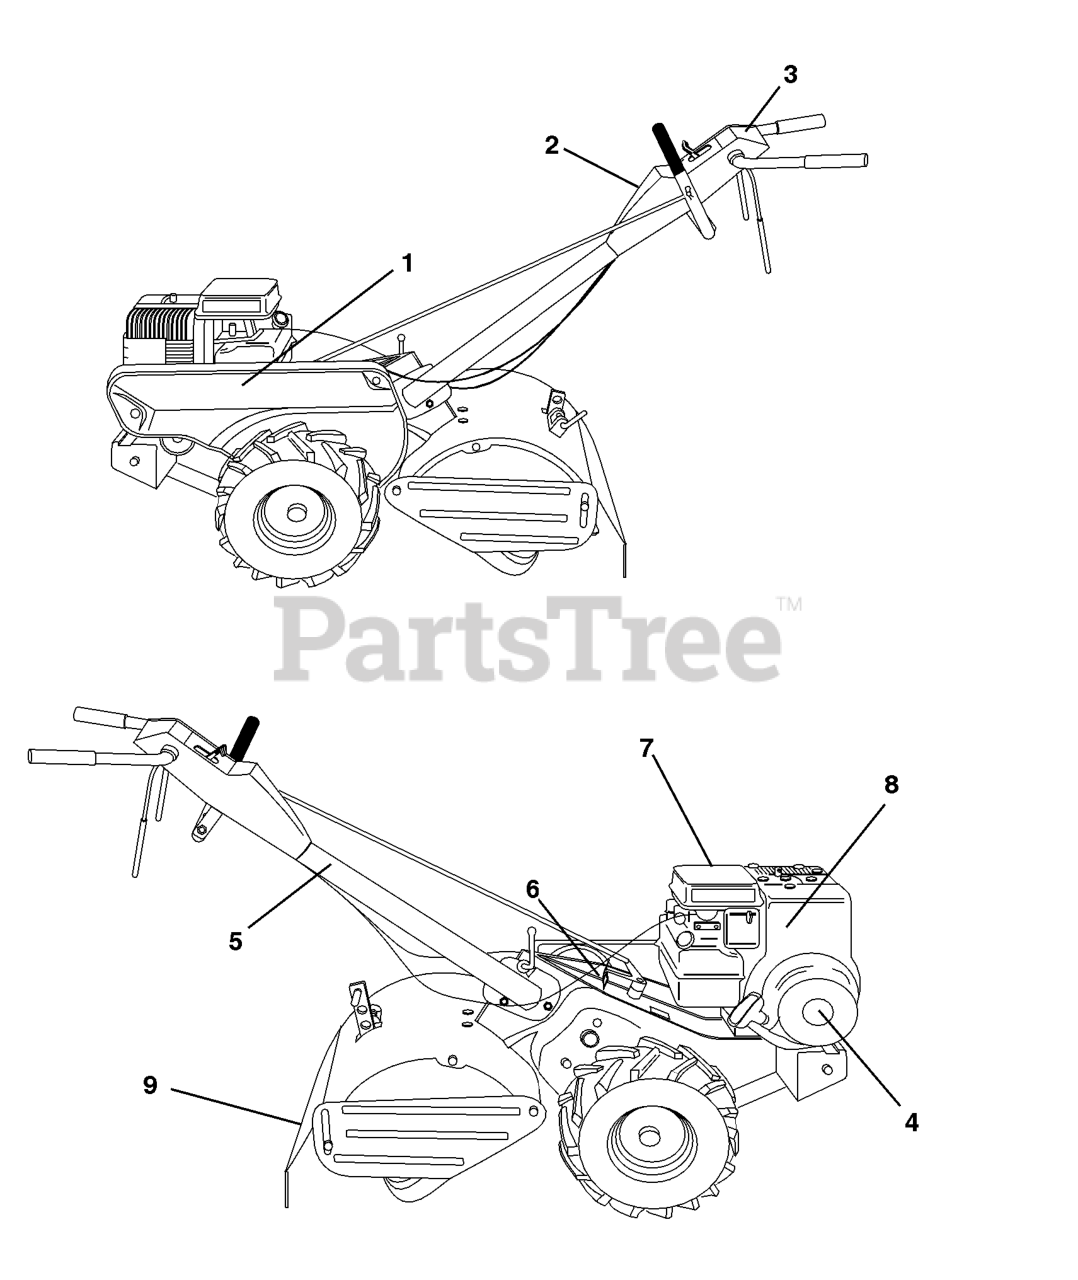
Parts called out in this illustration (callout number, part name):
1	Decal, Logo
2	DECAL, LOGO
3	DECAL, LOGO
5	DECAL TI (2 2)
6	Decal, Shift Indicator
7	DECAL -CAUTION
8	DECAL, B & S ENGINE
9	DECAL TI
